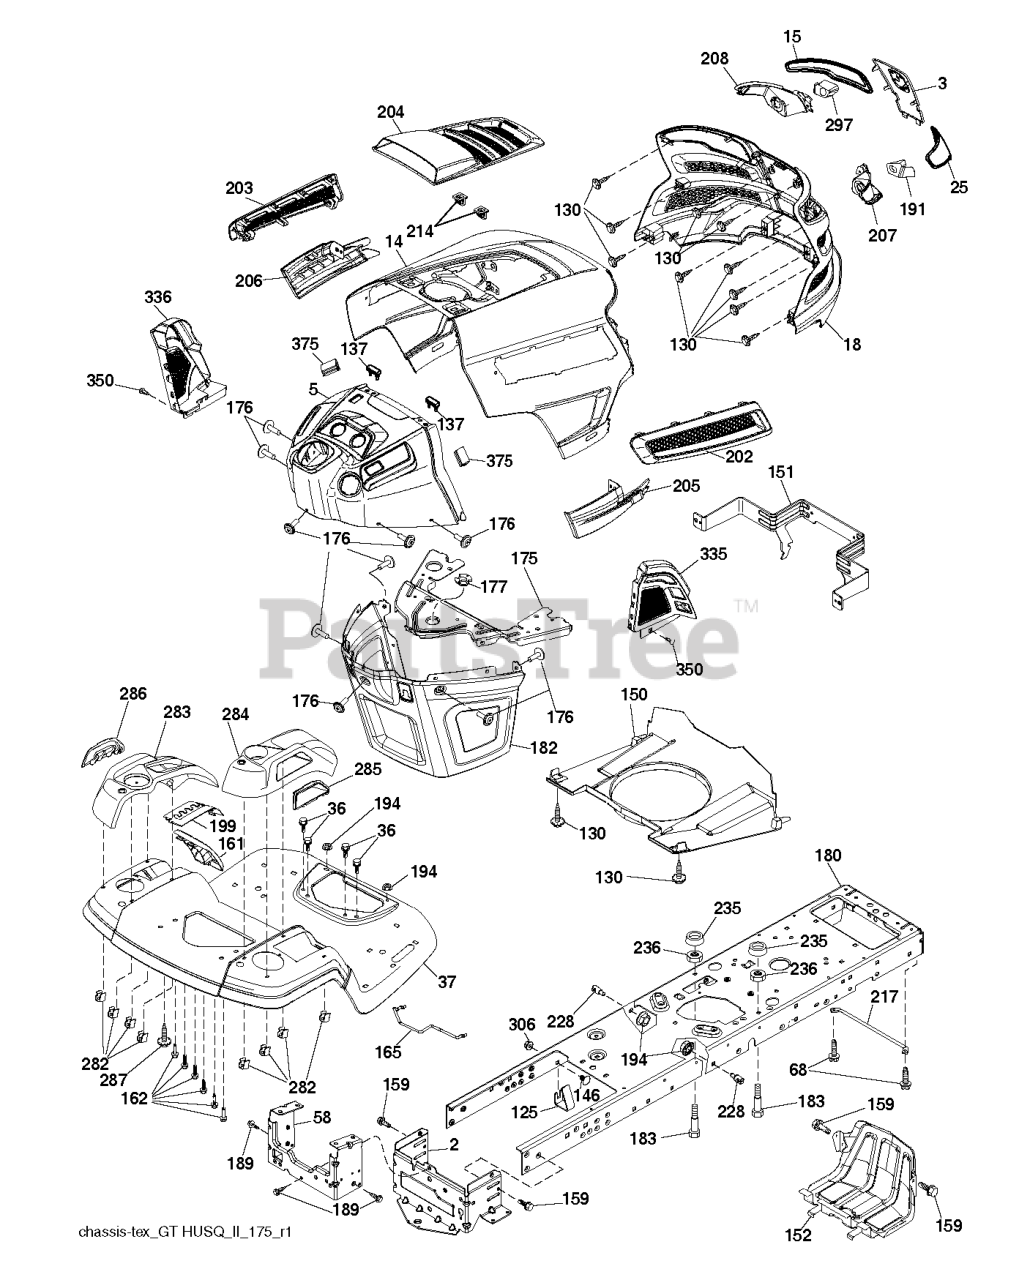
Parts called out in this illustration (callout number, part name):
2	DRAWBAR.LOWER.2PC.18/22
3	APPLIQUE.SUBASM.GT.HUSQ.II
5	RP DASH.UPP.GT2.DUAL.RD.PTO.MC
14	HOOD.ASM.HUSQVARNA.GT.TEX.422
15	LENS.HEADLIGHT.LH.GTII.2011
18	GRILLE.SUBSTRATE.2011.
25	LENS.HEADLIGHT.RH.GTII.2011
36	SCREW 5/16"
37	FENDER.TLT.FS.W/CPH/FW/RSF.668
58	DRAWBAR UPPER 2PC SMALL FENDER
68	Screw 5/16-18 x 1/2 Hex, Self Tapping 5/16-18 x 1/2
125	CLIP.FUEL.LINE
130	SCREW.#10 X 0.750.BOS
137	BUMPER DASH
146	BOLT.RDHD.SHT.SQNK.3/8-16X5/8
150	AIR.DUCT.GTV.BLACK
151	BRACKET.PIVOT.HOOD.GT.HUSQ.II
152	SHIELD.BROWNING.PNT.GT.V2
159	SCREW, 3/8-16X3/4
161	WINDOW.FUEL.LT.HUSQ.TEX.498
162	SCREW.HI-LO.CONSOLE
165	SUPPORT.TANK.REAR.B/TE
175	PLATE.CROSSMEMBER.HUSQ
176	SCREW.#10-24X5/8.RN.QU
177	BUSHING STEERING
180	CHASSIS.TEX.BOLTED
182	DASH.LOWER.COMMON.12V.ADAPTOR
183	BOLT.5/16-18X1-1/4 FULL THD
189	SCREW
191	INSERT.REFLECTIVE.RH.HUSQ.GTII
194	NUT LOCK HEX FLANGE 5/16-18
199	PLATE.DECK.LIFT.HUSQ.LT
202	VENT.SIDE.RH.GT.HUSQ.II.
203	VENT.SIDE.LH.GT.HUSQ.II.498
204	VENT.TOP.HUSQ.GT2
205	SIDE.TRIM.RH.GT.HUSQ.II
206	SIDE.TRIM.LH.GT.HUSQ.II.GRAY
207	BEZEL LIGHT.RH.GT.II.MYLAR
208	BEZEL LIGHT.LH.GT.II.MYLAR
214	CLIP.RETAINER.TINNER.
217	ROD.PIVOT.HOOD
228	STUD.FASTNER.W/ANTI-ROTATE
235	SPACER FENDER
236	NUT.CENTERLOCK.5/16-
282	CLIP.RETAINER.CONSOLE.LT.HUSQ
283	CONSOLE.ASM.LFT.RSF.HUSQ.LT
284	CONCOLE.CNTRL.PDL.HUSQ.LT.498
285	CONSOLE INSERT RH
286	CONSOLE.INSRT.LH.HUSQ.LT.BLACK
287	SCREW 1/4X20
297	INSERT.REFLECTIVE.LH.HUSQ.GTII
306	NUT LOCK FLG 3/8-16 UNC
335	COVER.LOWER.DASH.RH.BLACK
336	COVER-LH.LOWER.DASH.GT2.BLACK
350	CLIP.X-MAS.TREE
375	BUMPER CLIP-ON. DASH 1"
